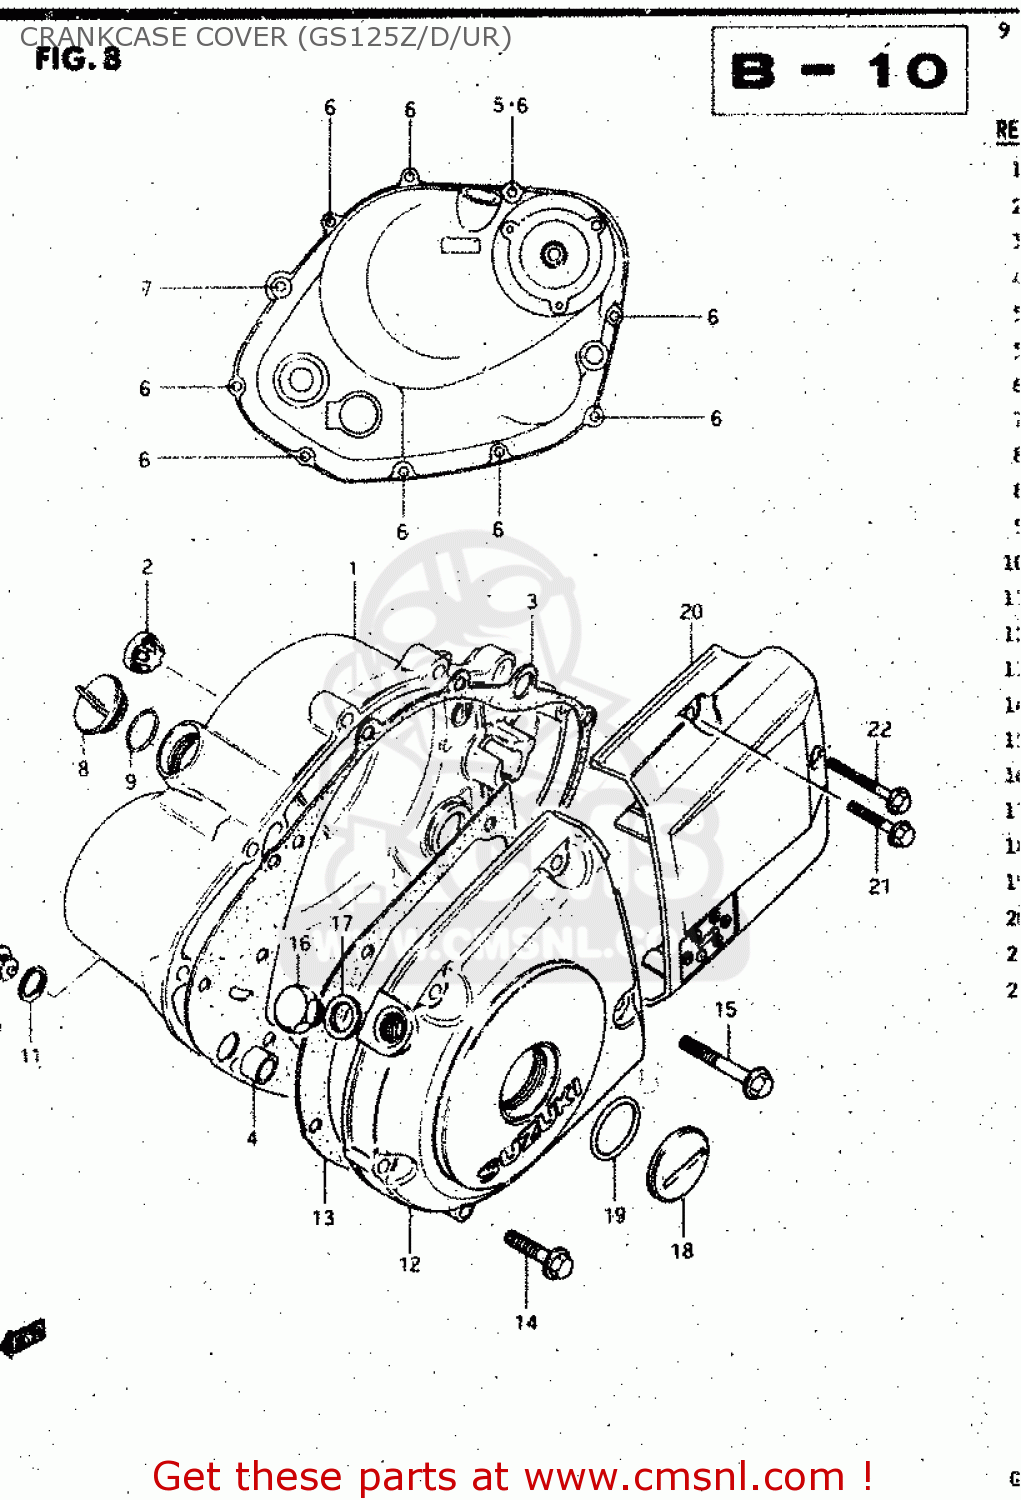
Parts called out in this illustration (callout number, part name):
1	COVER,CLUTCH
2	LENS,OIL LEVEL CHECK
3	GASKET,CLUTCH COVER (NAS)
4	PIN
5	GASKET(5.8X13X1.2) (NAS)
6	BOLT
7	BOLT
8	PLUG
9	O RING(D:3.1,ID:16.8)
10	PLUG, OIL CHECK
11	GASKET(13.8X18.8X4.8) (NAS)
12	COVER,MAGNETO
13	GASKET,MAGNETO COVER (NAS)
14	BOLT
15	BOLT
16	PLUG,12X9
17	GASKET(12.1X16.2X3.7) (NAS)
18	PLUG
19	O RING(D:3.1,ID:22.7)
20	COVER,ENGINE SPROCKET
21	BOLT
22	BOLT
